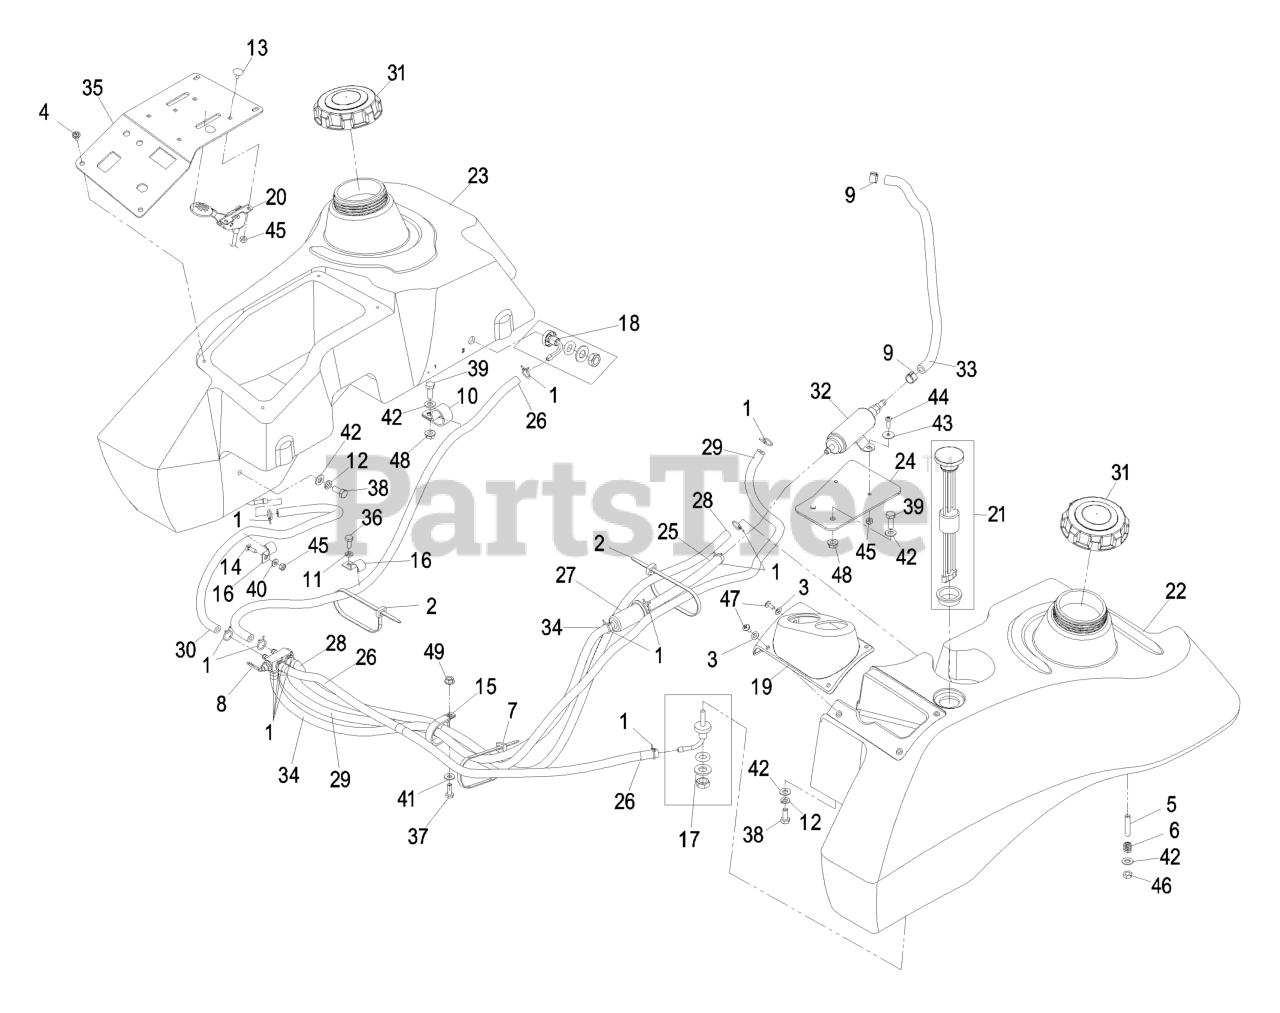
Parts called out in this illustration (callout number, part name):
2	TIE-PLASTIC
3	WASHER-SPRING
4	SCREW-PPH
5	STUD
6	SPRING-TANK, FUEL
7	TIE-PLASTIC
8	VALVE-FUEL, DUAL FLOW
9	CLAMP-HOSE, FUEL
10	CLIP-LOOM
11	WASHER-LOCK
12	WASHER-LOCK
13	BOLT-CARR
14	BOLT-CARR
15	CLIP-LOOM
16	CLIP-HALF, LOOM
17	FITTING-FUEL, BULKHEAD
18	FITTING-FUEL, BULKHEAD
19	BEZEL, GAGE XP LH TANK
20	CONTROL-THROTTLE
21	KIT, CT FUEL GAGE REPL.
24	BRACKET, FUEL PUMP
25	HOSE-FUEL
26	HOSE-FUEL
27	Kawasaki P/N 49019-1055 Fuel, Filter
28	HOSE-FUEL
29	HOSE-FUEL
30	HOSE-FUEL
31	CAP-FUEL, GAS
32	PUMP-FUEL
33	KIT,FUEL LINE W/ CLAMPS
34	HOSE-FUEL
35	PANEL,CONTROL W/DECALS
36	SCREW-HH
37	SCREW-HH
38	SCREW-HH
39	SCREW-HH
40	WASHER-FLAT
41	WASHER-FLAT
42	WASHER-PLAIN
43	WASHER-FLAT
44	SCREW-PPH
45	NUT-LOCK, NI
46	NUT-LOCK, NI
47	SCREW-PTH
